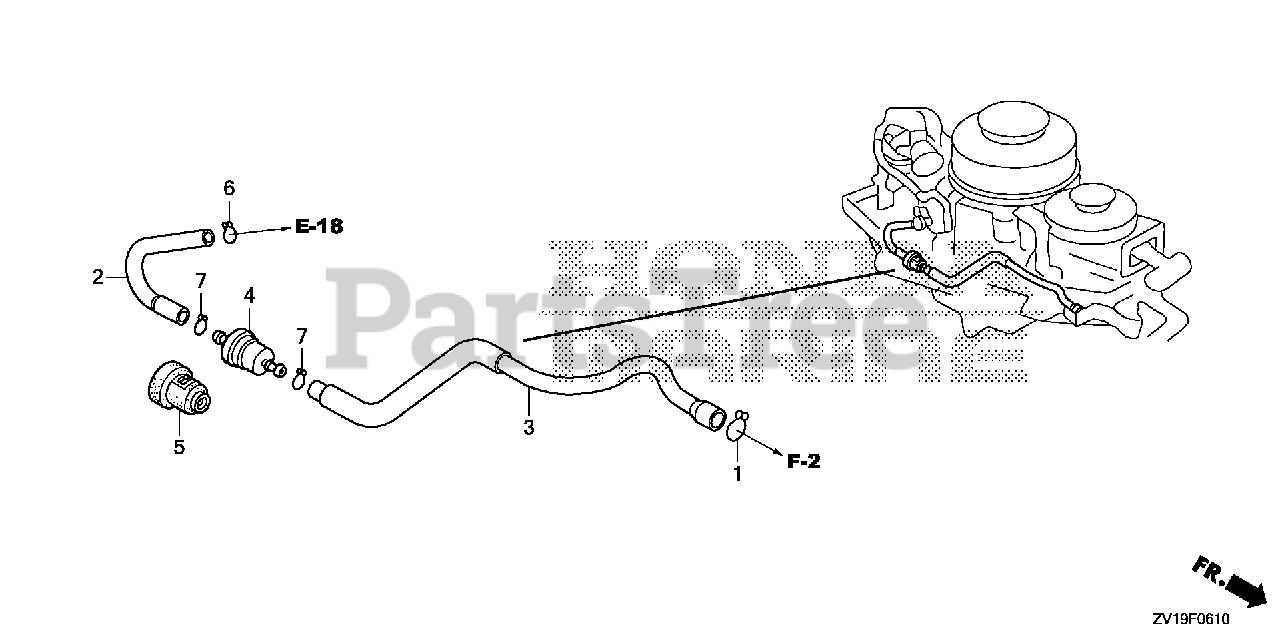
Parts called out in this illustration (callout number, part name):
1	CLIP, TUBE (ENGINE NO.)
2	TUBE B, FUEL (ENGINE NO.)
3	TUBE A, FUEL (ENGINE NO.)
4	FILTER, FUEL
5	SUSPENSION, STRAINER
6	CLIP, TUBE (B8)
7	CLIP, TUBE (B10)
